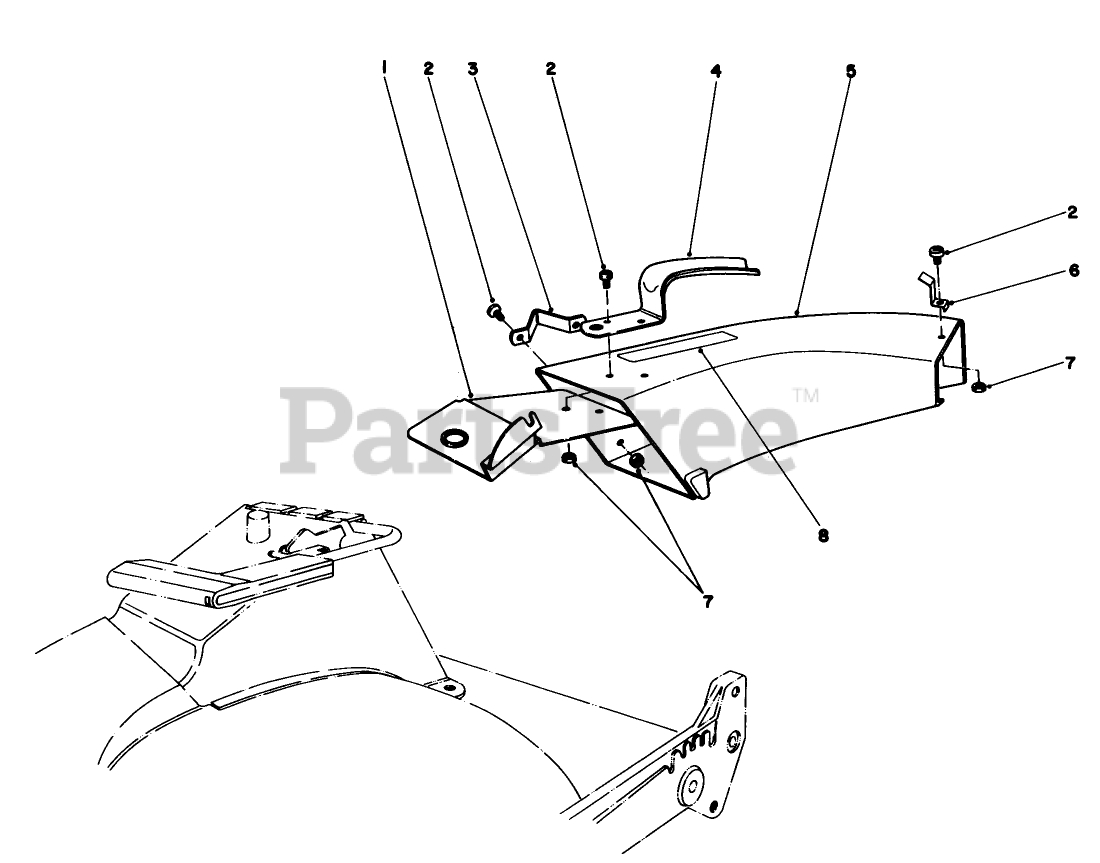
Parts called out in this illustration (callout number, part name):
2	10-24 X 5/8 PAN HD MS
4	CHUTE HANDLE
5	ORDER 59168 W.G.#
7	NUT-LOCK, NI
